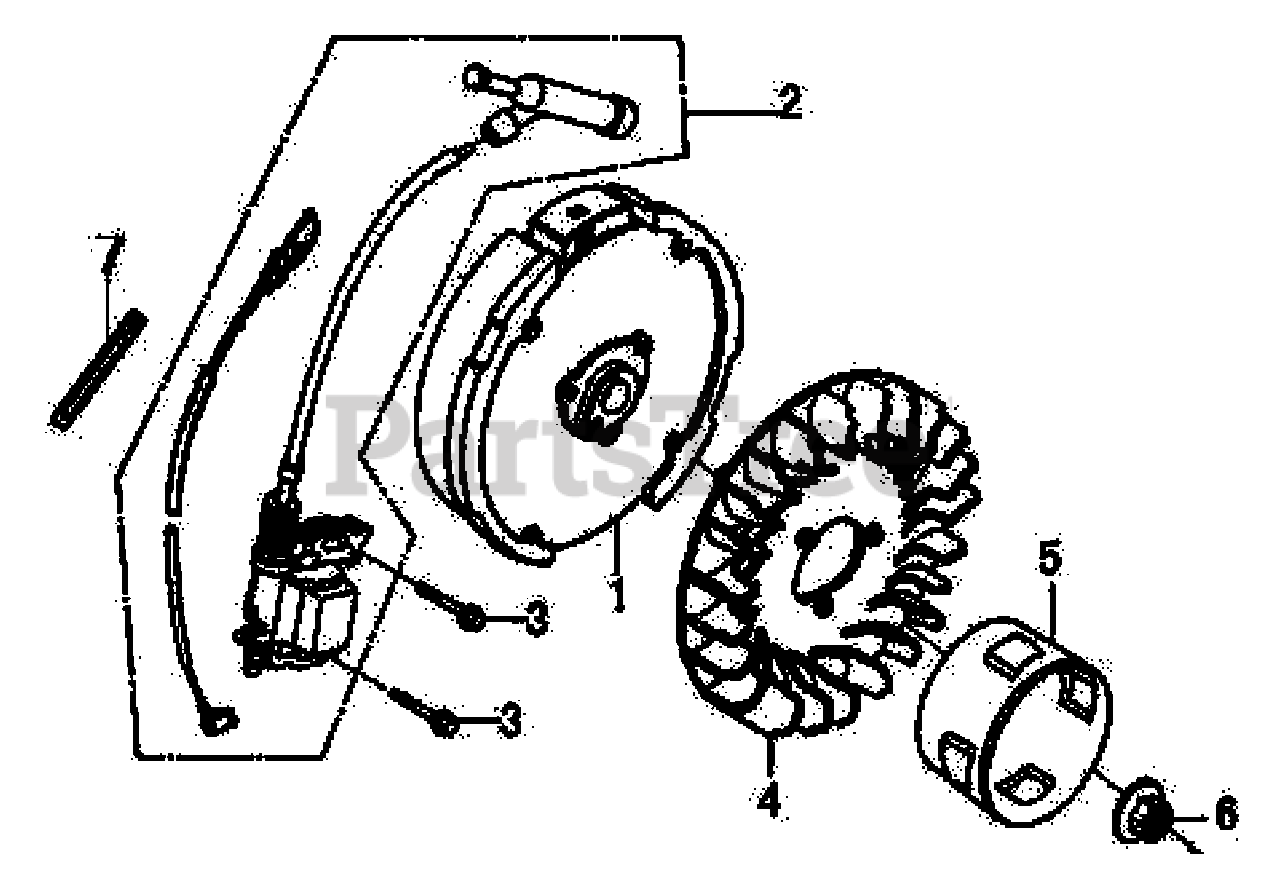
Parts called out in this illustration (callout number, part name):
2	COIL ASSEMBLY, IGNITION
3	BOLT, FLANGE, 6X25
4	FAN, COOLING
5	PULLEY, STARTER
6	NUT, SPECIAL
7	CABLE CLEAT
